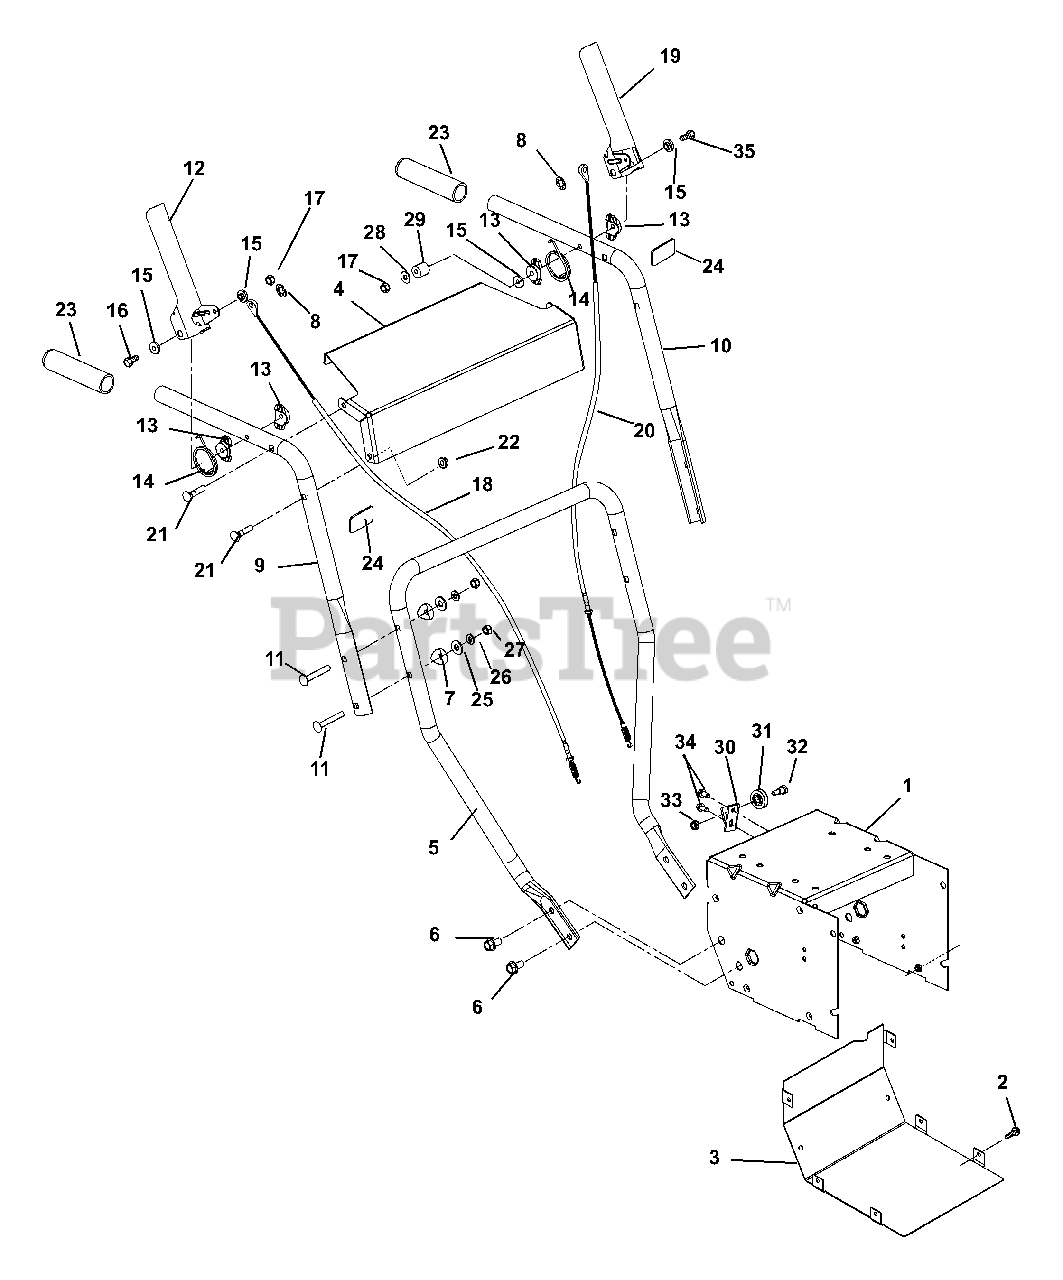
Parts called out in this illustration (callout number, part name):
2	@SCR-TAP .25-20X.50 HWH TR YWZ
3	COVER, BOTTOM
4	CONTROL PANEL W/DECAL
5	HANDLEBAR, LOWER
6	BLT-SERHFWH .38-16X.75 YWZC
7	SPACER, HANDLEBAR
8	RG-RTNG-EXT .250X.010
9	HANDLEBAR, UPPER RH
10	HANDLEBAR, UPPER LH
11	@BLT-RDHDSQNK .31-18X2.25 G5YZ
12	PADDLE, CLUTCH - RH COMPACT
13	SPACER, HANDLEBAR
14	SPRING, TORSION
15	BSHG, FLG .266X.42X.150 PM
16	@BLT-HEX .25-20X2.50 GR5 YWZC
17	NUT-JAM-NYL .250-20 W/INSERTYZ
18	AUGER CABLE, ST520 SINGLE SPD
19	PADDLE, CLUTCH - LH COMPACT
20	DRIVE CABLE, ST520 SINGLE SPD
21	BLT-RDHDXLSQNK .31-18X1.5 G5YZ
22	@NUT-LK-TOP-FLG .31-18 YWZC
23	HANDLE GRIP
24	BUMPER PAD
25	@WSHR-FL-STL.38X.875X.083 YWZC
26	@WSHR-LK .31X.078 REG YWZC
27	@NUT-LK-NYL .312-18 YWZC
28	@WSHR-FL-STL.281X.62X.065 YWZC
29	BSHG, SLV .266 X .750 X .750
30	BRACKET, CABLE PULLEY
31	PULLEY, CABLE
32	BOLT, SHLDR-.375X.375X.25-20
33	@NUT-LK-TOP-FLG .25-20 YWZC
34	@SCR-TAP .25-20X.50 HWH TR YWZ
35	@BLT-HEX .25-20X3.25 YWZC
